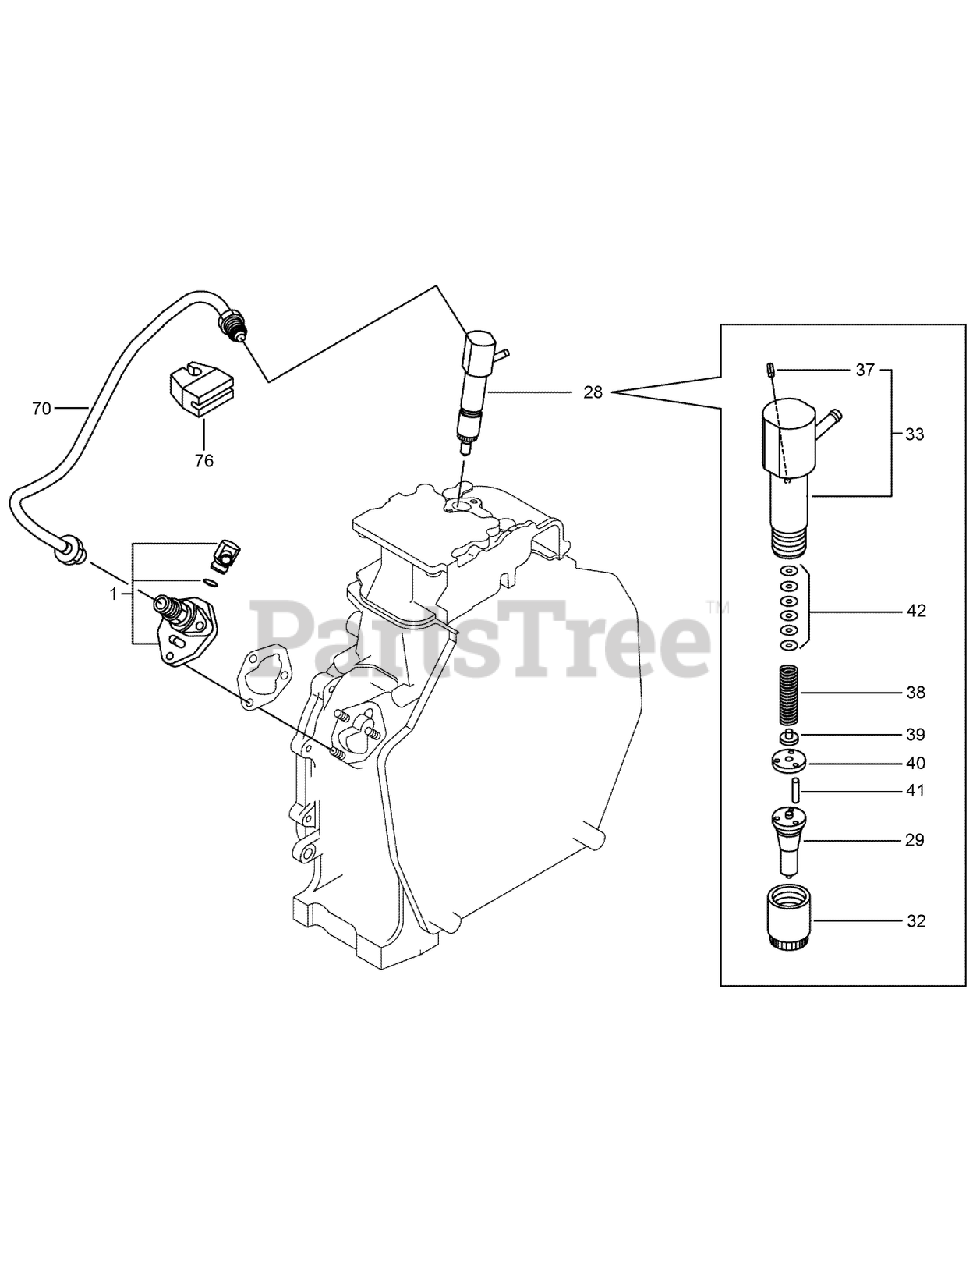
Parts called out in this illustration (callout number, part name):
1	FUEL INJECTOR PUMP ASM
28	FUEL INJECTON VALVE ASM
29	FUEL INJECTON NOZZLE ASM
33	NOZZLE HOLDER ASM
37	PIN-SPRING
38	SPRING
39	SEAT-SPRING
42	SHIM SET
70	PIPE-INJECTION, FUEL
76	SUPPORT-PIPE
